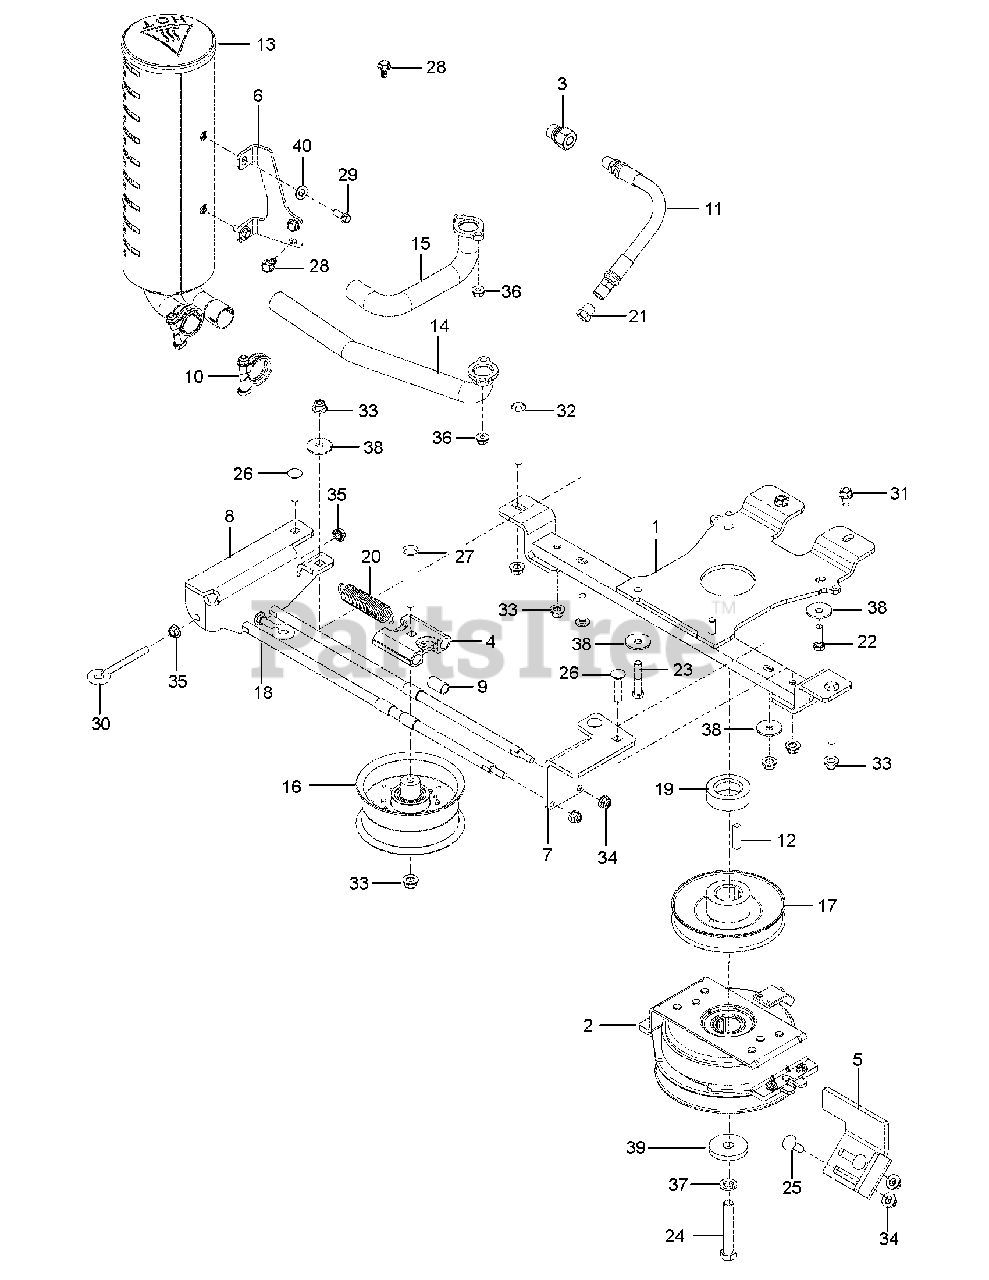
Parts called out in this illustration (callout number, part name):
2	CLUTCH OGURA GT2.75; 6.85" OP
3	ADAPTER, OIL DRAIN
4	BLOCK STANDON DECK DRIVE TENSI
5	BRACKET STANDON CLUTCH ANTI-RO
6	Muffler Mounting Bracket
7	BRACKET STANDON LH DRIVE TENSI
8	BRACKET STANDON RH DRIVE TENSI
9	Sleeve Bushing, Plastic
10	CLAMP 33 MM EXHAUST TUBE
11	HOSE.ASSEMBLY.OIL.DRAIN
12	KEY, 1/4 SQ X 1 1/4
13	MUFFLER.ASSY.STAND.ON.VERTICAL
14	MUFFLER.LH.HEADER.751V
15	MUFFLER.RH.HEADER.751V
16	PULLEY.5"X2.03".FLAT.IDLER
17	PULLEY, ENGINE
18	SHAFT.TNSNR.DRIVE.DECK.STANDON
19	SPACER ENGINE PULLEY
20	SPRING STANDON DECK DRIVE EXTE
21	PLUG OIL DRAIN
22	BOLT
23	CAP.SCREW.HEX.HD.3/8-16
24	CLUTCH BOLT7/16-20X2.5 GR596HR
25	RHSNB 5/16C X 1
27	BOLT.RDHD SQNK 3/8-16 X 3-1/2
29	BOLT 5/16-18 X .75 HEX FLANGE
30	EYE BOLT 5/16 X 3.50
31	SCREW 3/8-16X1
33	NUT 3/8-16 HEX FLG NYLOC ZD
34	5/16-18 NYLOC FLANGE NUT
35	NUT 5/16C WHIZ
36	NUT.HEX.FLANGE.TOPLOCK
37	WASHER 7/16 LOCK
38	CONE WASHER
39	SPINDLE WASHER
40	WASHER, 3/8 DISC SPRING SPEC
